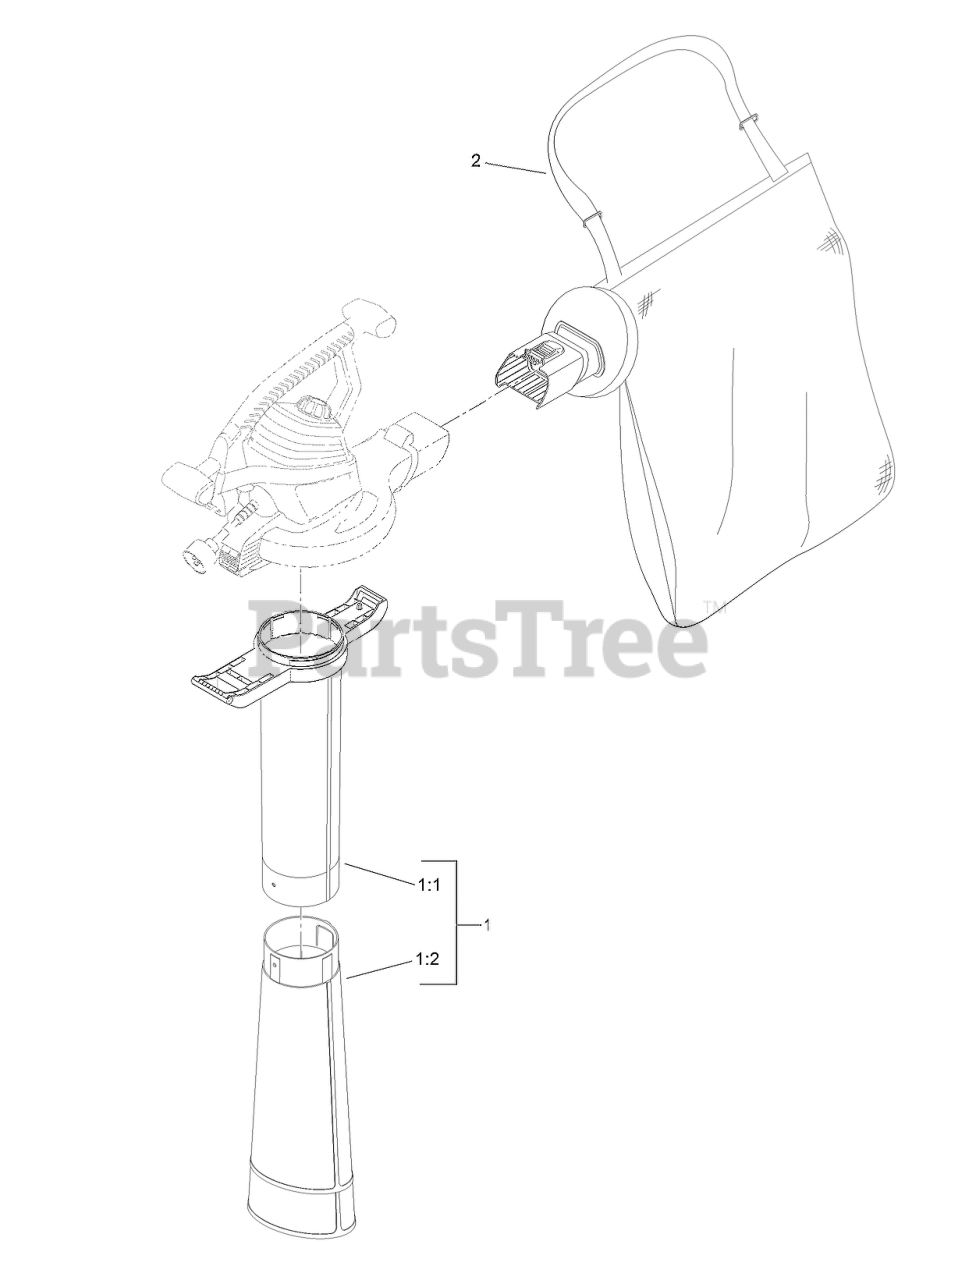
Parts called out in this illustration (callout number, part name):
1	VACUUM TUBE ASM
1:1	TUBE-VACUUM, UPPER
1:2	TUBE-VACUUM, LOWER
